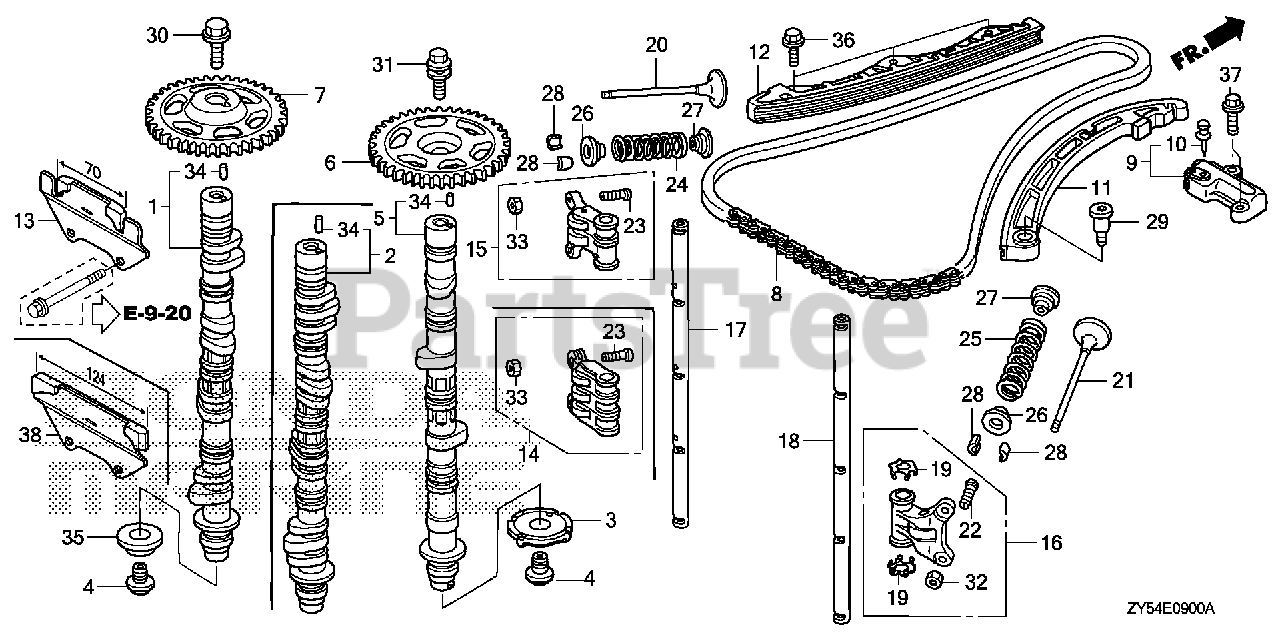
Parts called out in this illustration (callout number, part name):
1	CAMSHAFT, IN.
3	PLATE, TDC PULSE
4	BOLT, SEALING (14MM)
5	CAMSHAFT, EX.
6	SPROCKET, CAM CHAIN DRIVEN (46T)
7	SPROCKET, CAM CHAIN DRIVEN IN. (46T)
8	CHAIN (176L) (DAIDO)
9	TENSIONER ASSY., CAM CHAIN
10	STOPPER (TOOL)
11	ARM, CAM CHAIN TENSIONER
12	GUIDE, CAM CHAIN
13	GUIDE B, CAM CHAIN
15	ARM ASSY., ROCKER
16	ARM ASSY., EX. ROCKER
17	SHAFT, IN. ROCKER
18	SHAFT, EX. ROCKER
19	WASHER, THRUST
20	VALVE, IN.
21	VALVE, EX.
22	SCREW, TAPPET ADJUSTING
23	SCREW, TAPPET ADJUSTING
24	SPRING, IN. VALVE (PINK) (NIPPON HATSUJO)
25	SPRING, EX. VALVE (GRAY) (NIPPON HATSUJO)
26	RETAINER, VALVE SPRING
27	SEAT, VALVE SPRING
28	COTTER, VALVE (FUJI VALVE)
29	BOLT, TENSIONER PIVOT
30	BOLT, FLANGE (12X47)
31	BOLT, FLANGE (10X32)
32	NUT, TAPPET ADJUSTING (TOKAI TRW)
33	NUT, TAPPET ADJUSTING
34	PIN, DOWEL (4.2X10.3)
35	COLLAR, CAMSHAFT
36	BOLT, FLANGE (6X20)
37	BOLT, FLANGE (6X30)
38	GUIDE B, CAM CHAIN
